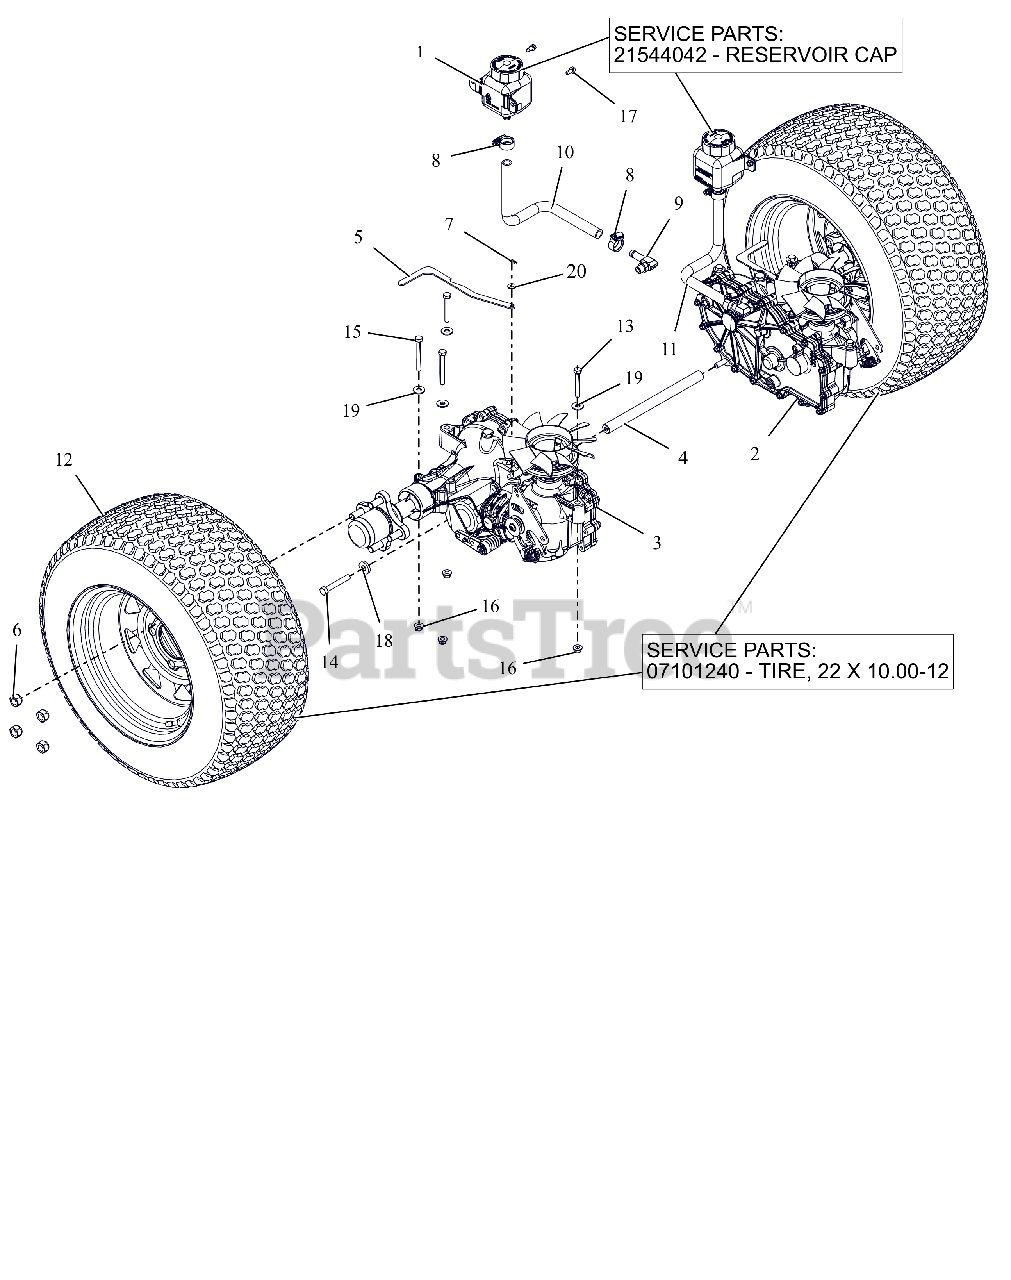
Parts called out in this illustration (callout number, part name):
1	TANK, EXPANSION
1	CAP, HYDRO RESERVOIR REPLAC.
2	TRANSAXLE, ZT3100 LH
3	TRANSAXLE, ZT3100 RH
4	SHAFT, TRANSAXLE SUPPORT
5	BRKT, VALVE DUMP
6	WHEEL NUT .500-20 YZ
7	PIN, HAIR #225 .072X1.09
8	CLAMP,.88 DIA. HOSE
9	FITTING, HYD (90 DEG)
10	HOSE, FORMED EXPANSION -HD RH
11	HOSE, FORMED EXPANSION -HD LH
12	ASM, WHL/TIRE 22X10.00-12 K500
12	TIRE, 22X10.00-12
13	BLT, HEX .31-18X2.25 G5 ZCC
14	BLT, HEX .38-16X2.50 G5 ZCC
15	BLT, HEX .31-18X2.75 G5 ZCC
16	NUT,LK-NYL-FLG .31-18 G5ZC120
17	SCR-TAP .25-20X.50 HWH ZCC
18	WSHR, FLT .406X1.00X.188 ZCC
19	WSHR,FLT .375X.875X.083 ZCC
20	WSHR,FLT .281X.625X.065 ZCC
